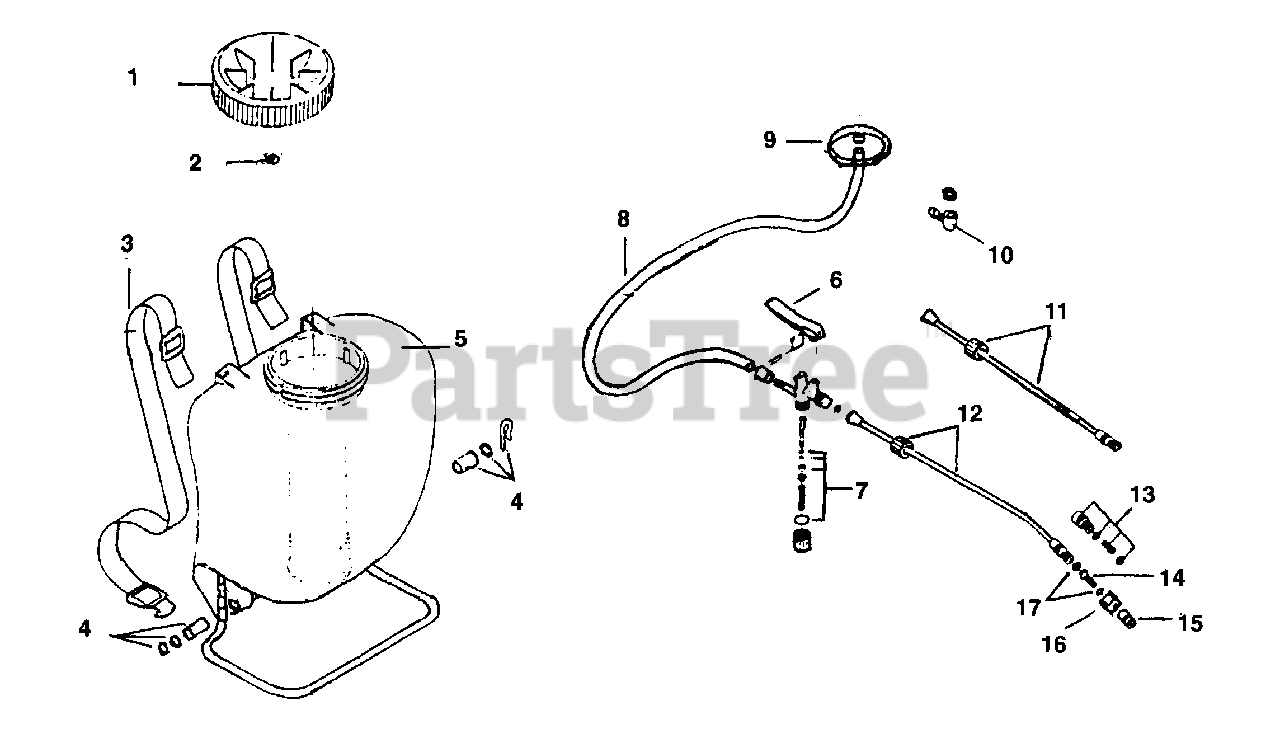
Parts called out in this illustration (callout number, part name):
1	CAP, TANK
2	CHECK VALVE FOR CAP
3	SHOULDER BELTS
4	NYLON BEARING ASSY
5	TANK WITH STAND
6	COMPLETE SPRAY PISTOL
7	"O" RING SET, SPRAY PISTOL
9	RETENTION CLAMP
10	90 DEGREE FITTING
11	EXTENSION TUBE 66.5"
12	SPRAY WAND
13	SPRAY STRAINER
14	ADJ. NOZZLE, BRASS
15	SPRAY TIP NOZZLE SET
16	NOZZLE HOLDER
17	"O" RING SET, SPRAY TIP
